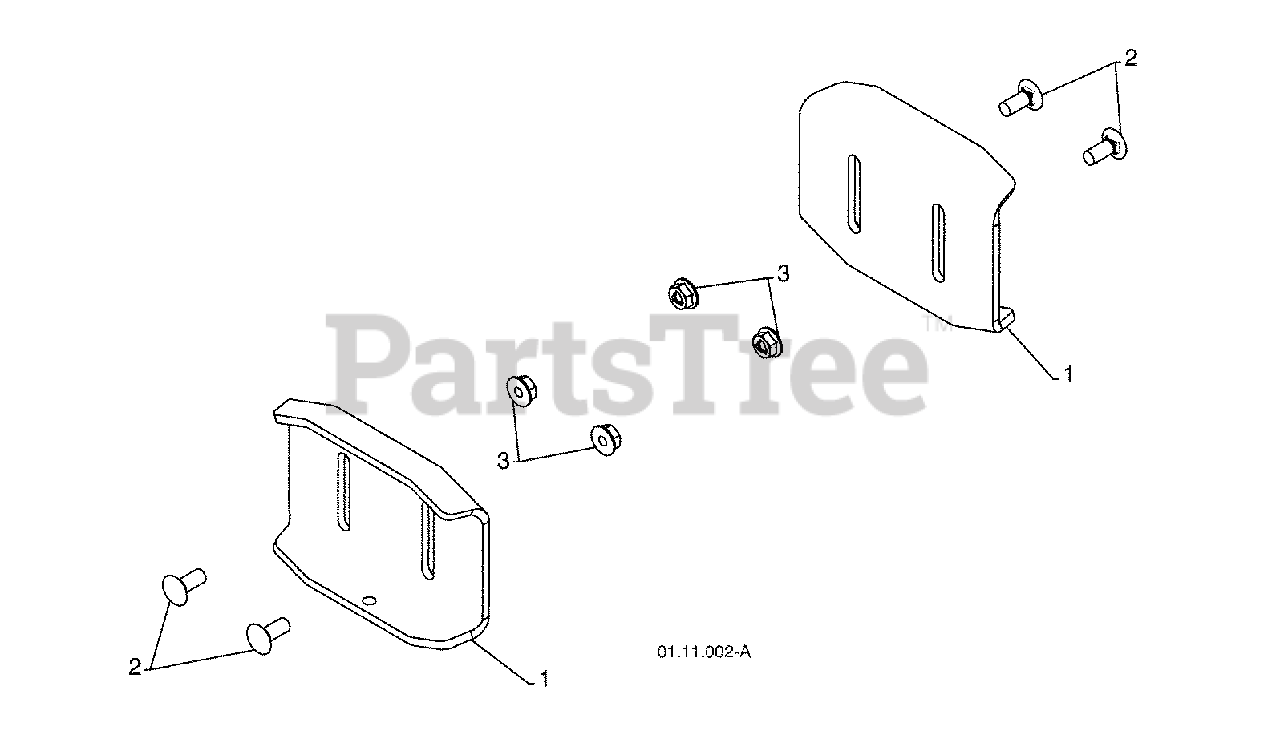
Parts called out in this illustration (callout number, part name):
1	SKID PLATE
2	CARRIAGE BOLT 5/16-18 X .750
3	NUT 5/16-18
